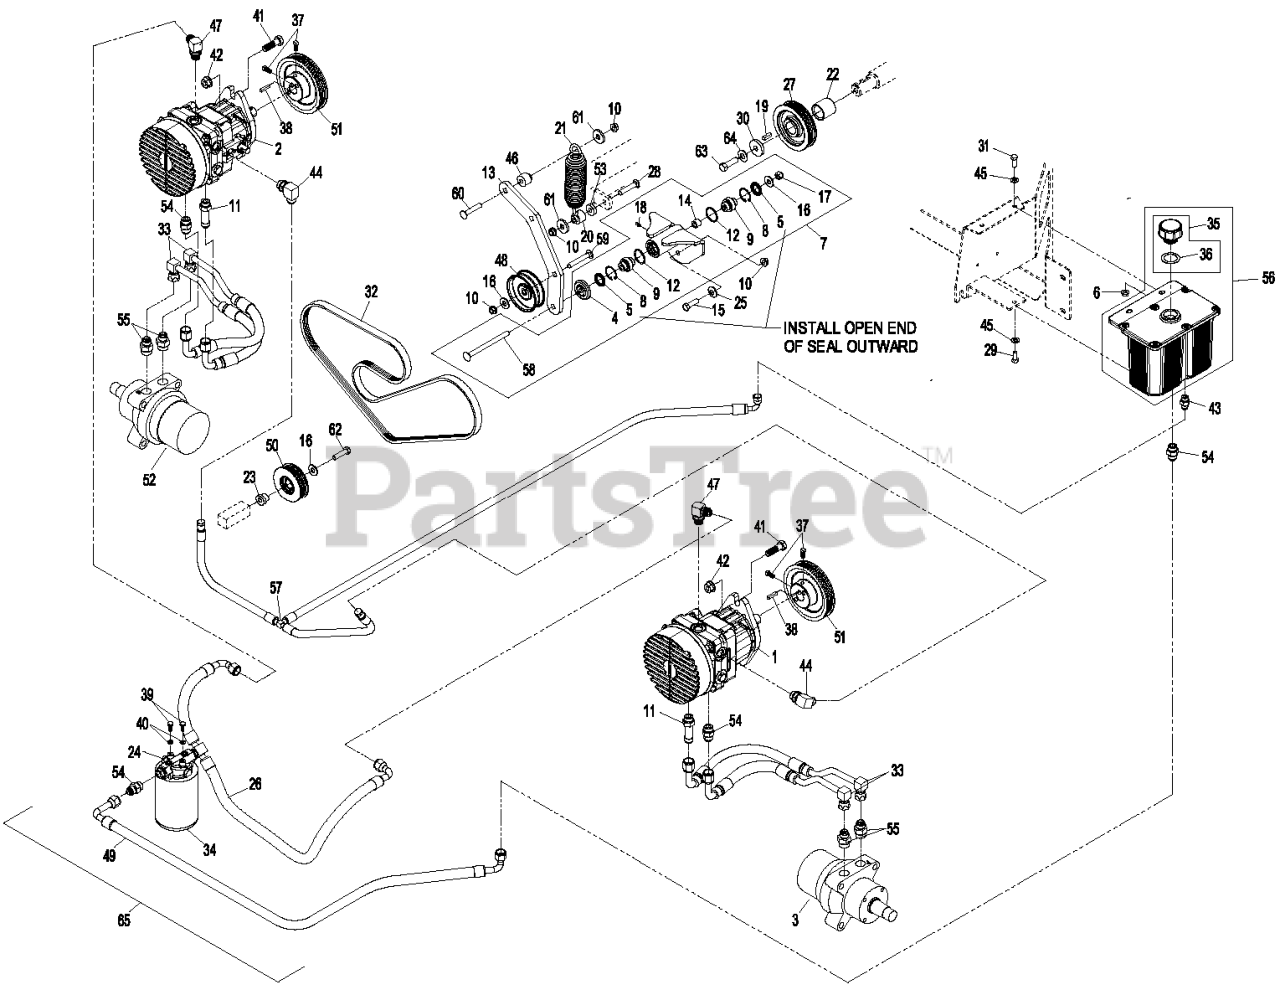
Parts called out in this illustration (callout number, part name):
1	PUMP, LH
2	PUMP, RH
3	HYD MOTOR ASM (CCW)
4	GUARD-TOP
5	SEAL-LIP, SINGLE
7	KIT,XS PUMP IDLER
8	RING-SNAP
9	BEARING-SPHERICAL
10	NUT-HHF, WHIZ
11	ADAPTER-STR, LONG
13	ARM, XS HYDRO TIGHTENER
15	SCREW-HH
16	WASHER-FLAT
17	NUT-LOCK, NI
18	FITTING-GREASE
19	KEY-SQUARE
20	SPACER-SPRING, FAN PUMP
22	SPACER,ENGINE SHEAVE
23	SPACER,LOWER FRAME IDLER
24	HEAD-FILTER
25	WASHER-BELLEVILLE
26	ASM, HOSE-PUMP INLET
27	SHEAVE,5K 4"PD POLY-V
28	BOLT-CARR, SHORT NECK
29	SCREW-HH
30	WASHER-CLUTCH
31	SCREW-HH
32	BELT, 5K 68.8
33	HYD HOSE ASM
34	FILTER,XP HYD 25 MICRON
35	KIT,HYD RES CAP W/GASKET
36	GASKET-CAP
37	SCREW-SET
39	SCREW-HH
40	WASHER-LOCK
41	SCREW-HH
42	NUT-HHF
43	FITTING-STRAIGHT
44	FITTING-ELBOW, 90 DEG
45	WASHER-PLAIN
47	FITTING-90 DEG
48	IDLER,FLANGED
49	ASM, HOSE-FILTER INLET
50	ASM,LOWER FRAME IDLER
51	SHEAVE,5K 5.0" PD POLY-V
52	HYD MOTOR ASM (CW)
53	SPACER-BRACKET, GUIDE
54	FITTING-STRAIGHT
55	FITTING-STRAIGHT
56	HYDRAULIC TANK ASM
57	ASM,CASE DRAIN HOSE
58	BOLT CARR 3/8-16X5
59	SCREW-CARR
60	SCREW-CARR
62	SCREW-HH
63	SCREW-HH
64	WASHER-SPRING
65	Asm, Filter W/Hoses
